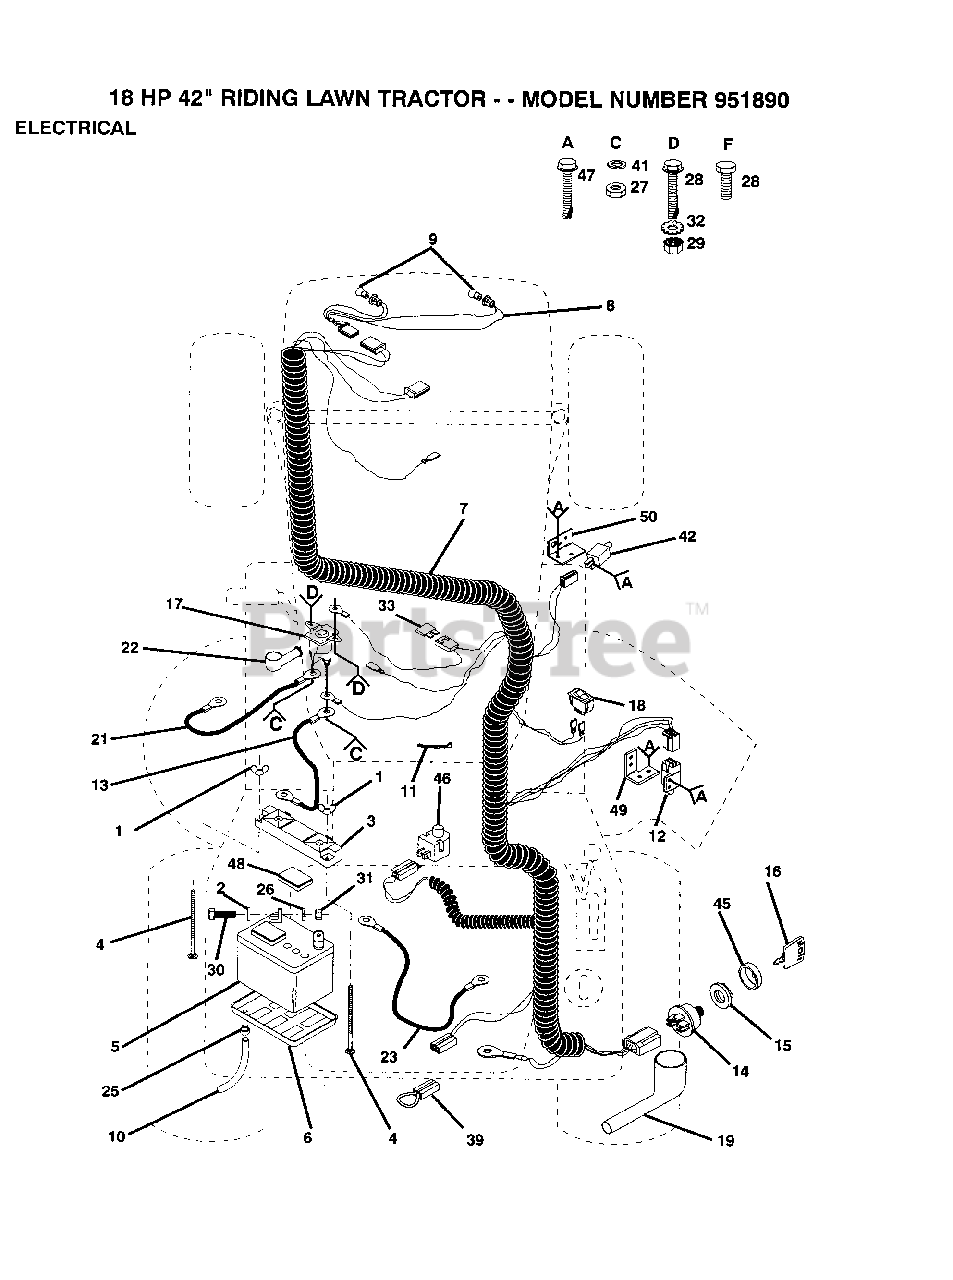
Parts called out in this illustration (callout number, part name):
2	WASHER
4	BOLT
6	"TRAY T, BATTERY"
7	"HARNESS,IGNITION"
11	WIRE TIE
12	SWITCH INTERLOCKT
13	CABLE-BATTERY T
15	NUT IGNITION
16	KEY
18	SWITCH LT
21	"CABLE T, BATTERY"
23	CABLE T
25	HOSE CLAMP T
26	LOCKWASHER
27	NUT
28	BOLT
29	NUT
30	BOLT LT
33	FUSE HYT
46	SWITCH SEAT
47	SCREW
48	"CAP,BATTERY "
